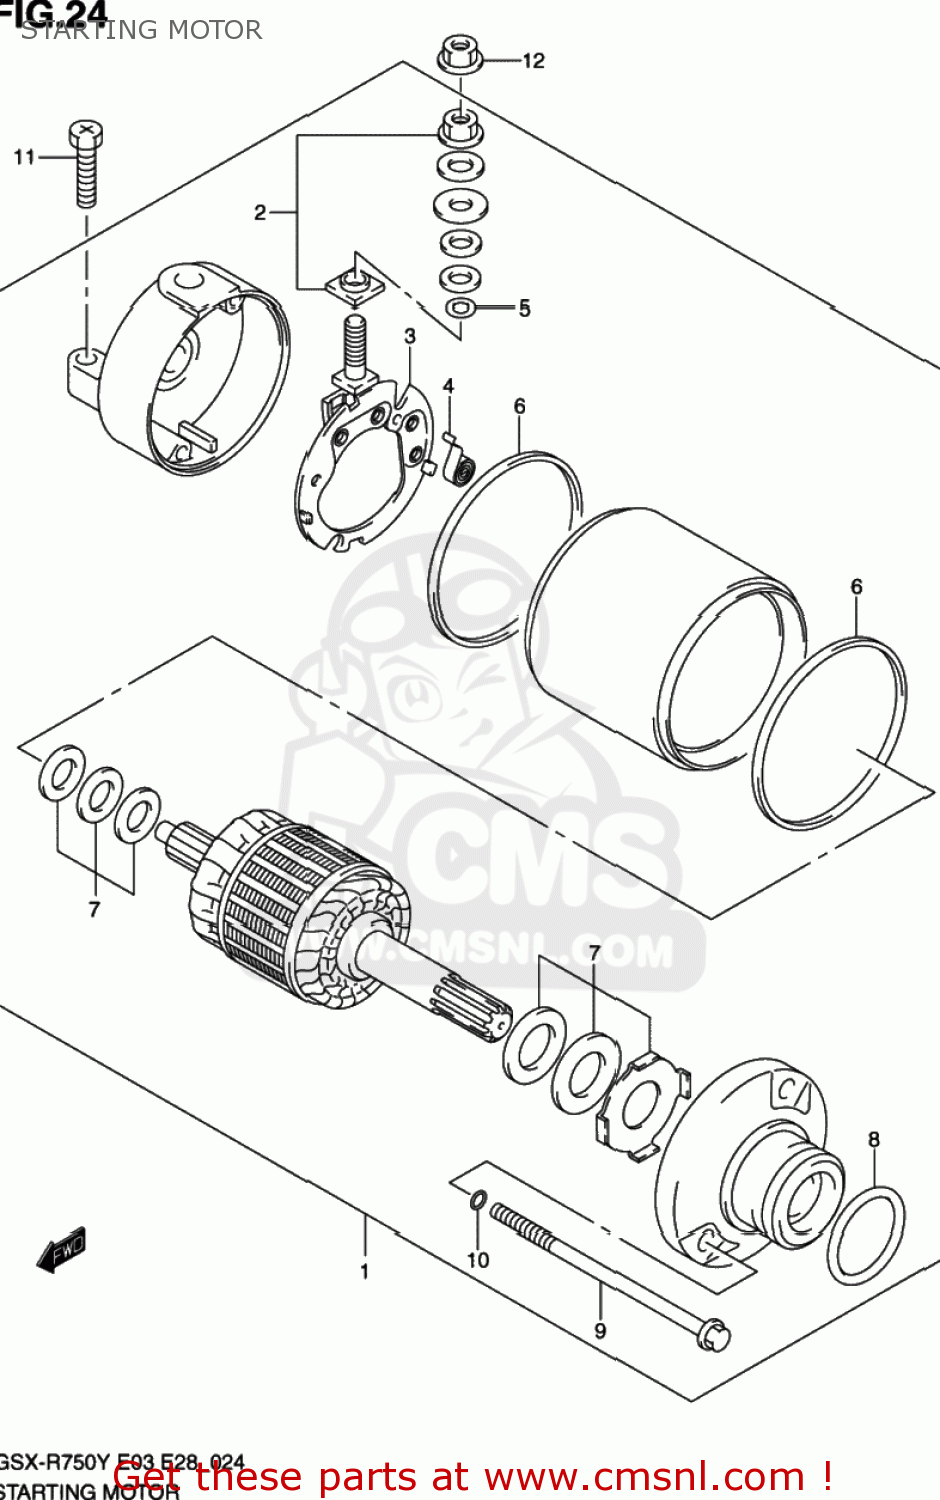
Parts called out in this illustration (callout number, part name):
1	MOTOR ASSEMBLY,STARTING
2	BRUSH TERMINAL SET
3	BRUSH HOLDER SET
4	SPRING,BRUSH
5	O RING
6	O RING
7	SHIM SET,STARTING MOTOR
8	O RING(D:3.1,ID:24.4)
9	BOLT
10	O RING
11	SCREW (6X25)
12	NUT
